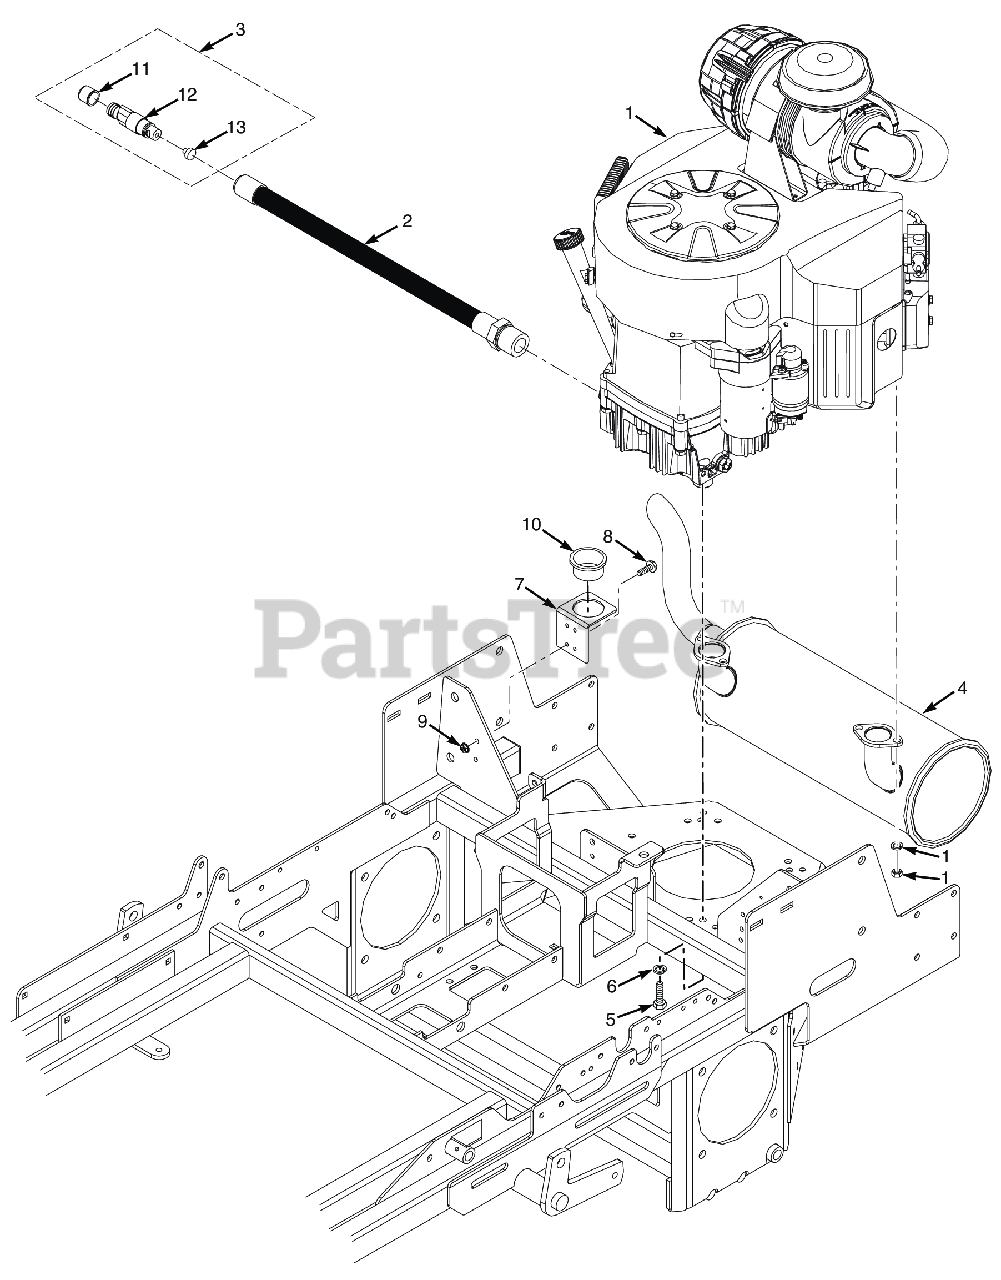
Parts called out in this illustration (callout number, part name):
1	Engine, Kawasaki 27FX (FX850)
1	Engine, Kohler 31CV-EFI (ECV860)
1	Engine, Kawasaki 31FX (FX921)
1	Engine, Briggs & Stratton 37 BV-EFI (61E8770002J1)
2	Hose Assembly, Engine Oil Drain - Kawasaki FS/FX
2	Hose, Oil Drain - Kohler CV & CV-EFI
2	Hose, OIl Drain, Briggs & Stratton
3	Valve Assembly, Oil Drain
4	Muffler, Kawasaki FX850 - SCZ
4	Muffler, Kohler (ECV860)- SCZ
4	Muffler, Kawasaki FX921 - SCZ
4	Muffler, Briggs & Stratton - 37 BV-EFI
5	Bolt, Hex Head 3/8-16 x 1-1/4", Kawasaki FX / FS
6	Lockwasher, 3/8" Spring, Kawasaki FX / FS
7	Bracket, Oil Drain Hose
8	Screw, #8-32 x 1/2"
9	Nut, Elastic Stop #8-32
10	Bushing, Thick Panel Snap
11	O-Ring
12	O-Ring
